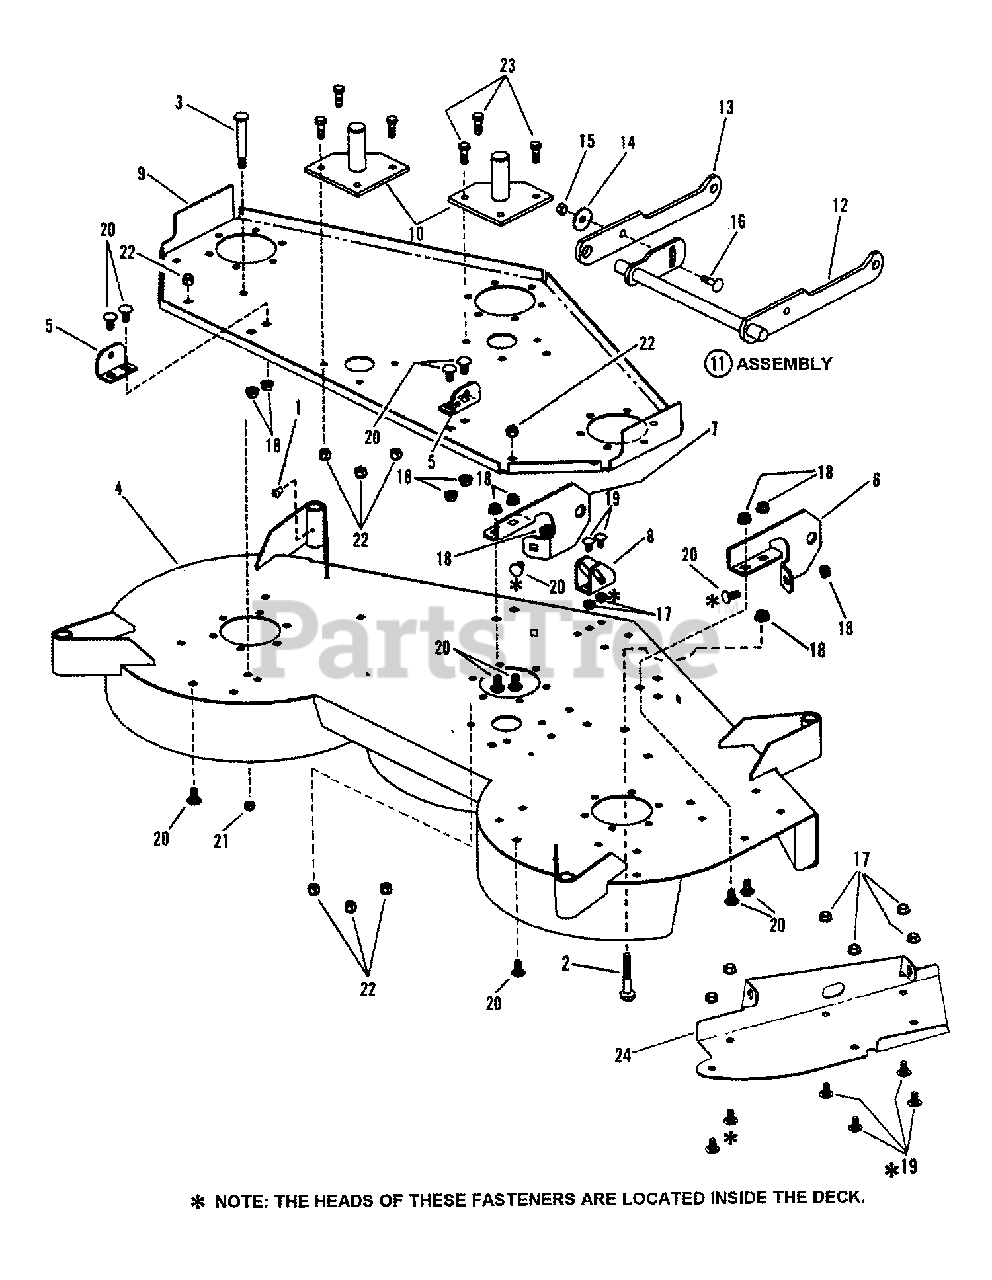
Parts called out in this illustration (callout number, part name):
1	LUBE FITTING, Straight (press-fit for .187 dia. Hole)
2	SCREW, 3/8-16 x 1-1/4" Hex Head Cap, GR5
3	SHOULDER BOLT, 3/8-16 thread
4	WELDMENT, 48" Deck
5	BRACKET, Rear Lift- 48" Deck
6	BRACKET, Front Hanger- Right Hand
7	BRACKET, Front Hanger- Left Hand
8	BRACKET, Front Hanger- 48" Deck
9	STIFFENER, 48" Deck
10	WELDMENT, Idler Plate
11	ASSEMBLY, Front Lift Arm- 97 Model Year (Incl. items 12 thru 16)
12	WELDMENT, Front Lift Arm
13	ARM, Lift
14	WASHER, Cone, 13/32 x 1-13/32" Diameter
15	NUT, 3/8-16 Hex
16	BOLT, 3/8-16 x 1-1/4" Square Neck Carriage, GR5
17	NUT, 5/16-18 Hex Flange Lock, GR5
18	NUT, 3/8-16 Hex Flange Lock
19	BOLT, 5/16-18 x 5/8" Short Neck Carriage, GR5
20	BOLT, 3/8-16 x 3/4" Short Neck Carriage, GR2
21	NUT, 5/16-18-3B Hex Nyloc
22	NUT, 3/8-16-3B Hex Nyloc
23	SCREW, 3/8-16 x 1" Hex Head Cap, GR5
24	BRACKET, Hinge
